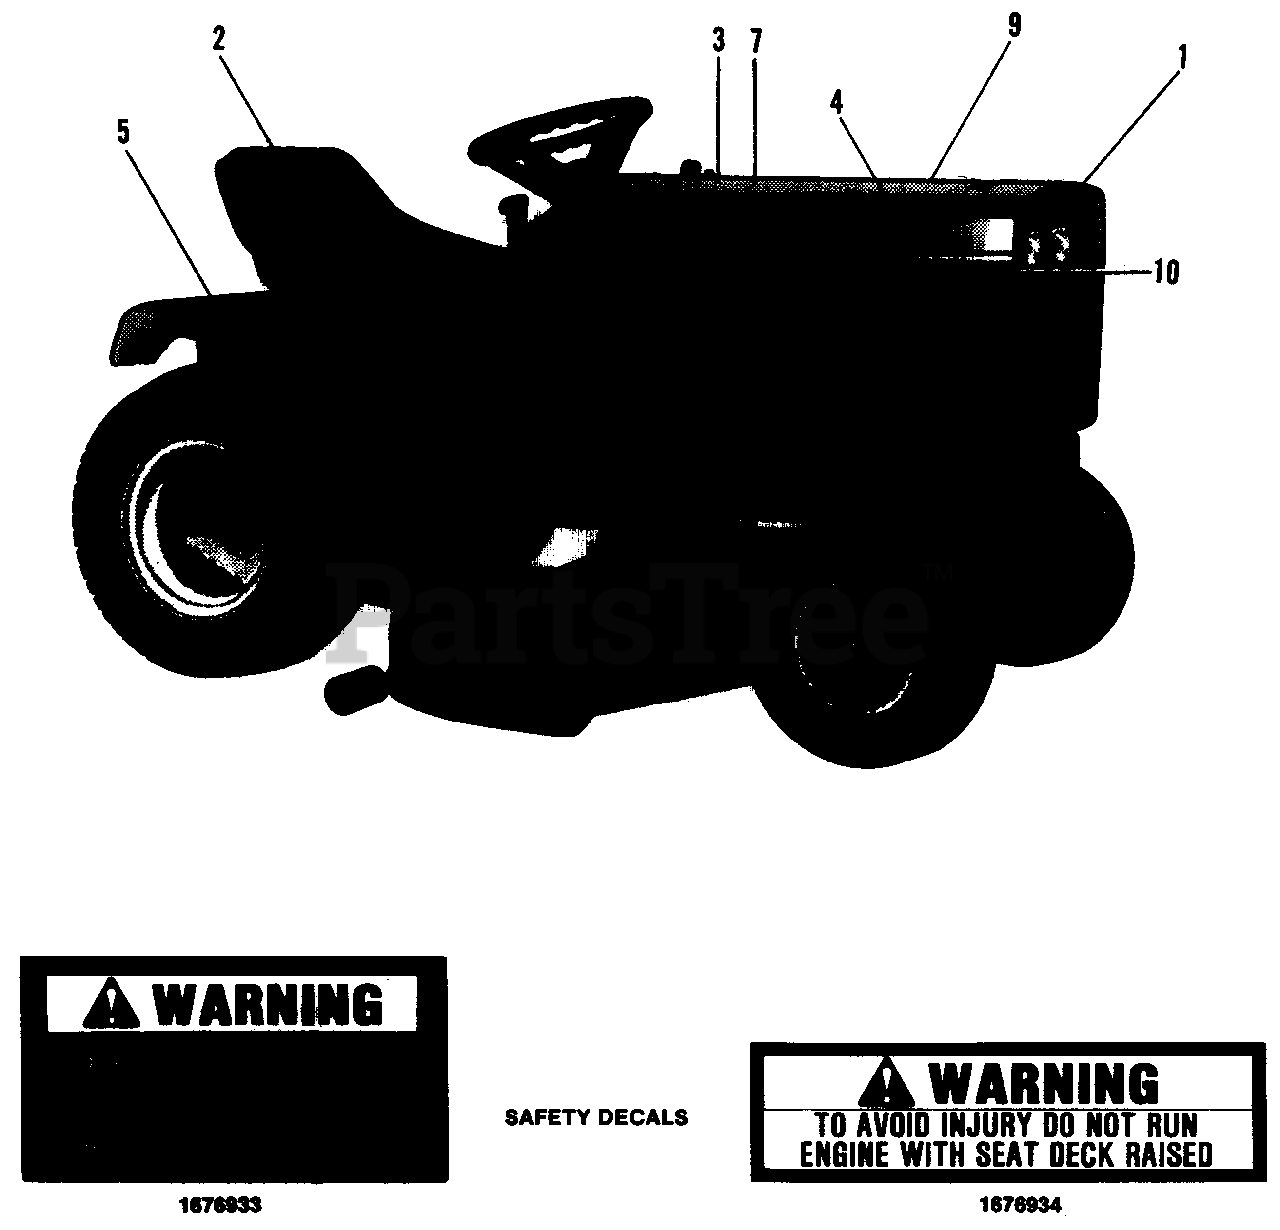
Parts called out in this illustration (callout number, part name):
1	DECAL, Grille
2	DECAL, Logo, USA
3	DECAL, Drive Belts & Mower Blades
4	DECAL, Hood Stripe, RH
5	DECAL, Logo, Simplicity
6	DECAL, Console, Hydro
7	DECAL, Touch-up Paint
8	DECAL, Dash
9	DECAL, Hood Stripe LH
9	DECAL, Adjustment, Mower Belt (Located on mower deck)
9	DECAL, Caution (Located under hood on right side of dash)
